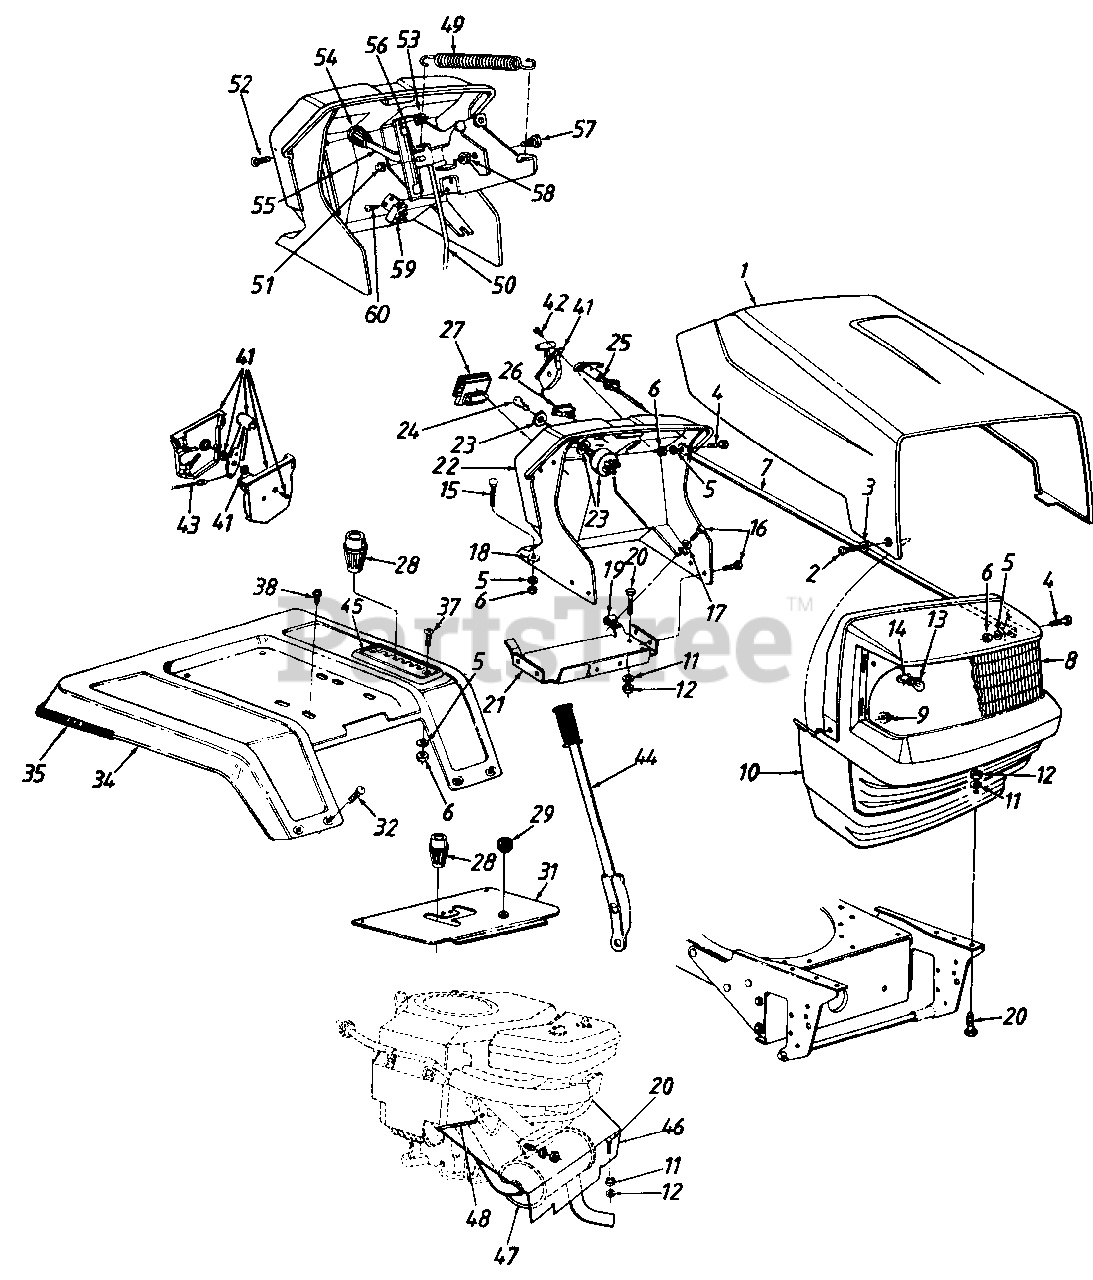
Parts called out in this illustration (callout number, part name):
1	N Hood
2	Shld. Bolt .375" Dia. x .125" Lt
3	Spr. Wash. .265" I.D. x .562" 0 0 O.D.
4	Hex Bolt 1/4-20 x .62" Lg.
5	L-Wash. 1/4" I.D.
6	Hex Nut 1/4-20 Thd.
7	N Grille Support Rod
8	N Headlight Lens
9	Flange L-Nut 1/4-28 Thd.
10	N Grille
11	L-Wash. 5/16" I.D.
12	Hex Nut 5/16-18 Thd.
13	Lamp
14	Socket
15	Carriage Bolt 1/4-20 x 1.0" Lg.
16	Hex Wash. Hd. TT-Tap Scr. 1/4-20 x .5" Lg.
17	Fl-Wash. .281" I.D. x .73" O.D.
18	Bolt Retainer 1/4" I.D.
19	Speed Nut 1/4-20 Thd.
20	Hex Bolt 5/16-18 x .75" Lg.
23	Ignition Switch
24	Ignition Key
25	Choke Control
26	Light Switch
27	Ammeter
28	Shift Knob
29	Ball Knob
31	Shift Cover
32	Carriage Bolt 1/4-20 x .5" Lg.
34	Fender
35	Trim Strip 81" Lg.
37	Truss Mach. Scr. #1/4-20 x .62"Lg.
38	Hex Wash. Hd. AB-Tap Scr. 5/16 x .75" Lg.
41	Throttle Box Ass'y.
42	Truss Mach. AB-Tap Scr. #10 x .5" Lg.
43	Throttle Control Wire
44	Lift Handle Ass'y.
45	Speed Selector Plate
46	Front Heat Shield
47	Muffler
48	Trim Strip 12" Lg.
49	N Ext. Spring 5.06" Lg.
50	N Deck Control Rod
51	Speed Nut 1/4" Rod
52	Truss Mach. Scr. 1/4-20 x .5" Lg.
53	Hex Sems Nut 1/4-2 Thd.
54	PTO Knob
55	N PTO Lever
56	N PTO Bracket
57	Shld. Bolt .437" Dia. x .162n
58	Hex L-Nut 5/16-18 Thd.
59	N Safety Switch
60	N Hex Wash. Hd. B-Tap Scr. #10 x .38" Lg.
